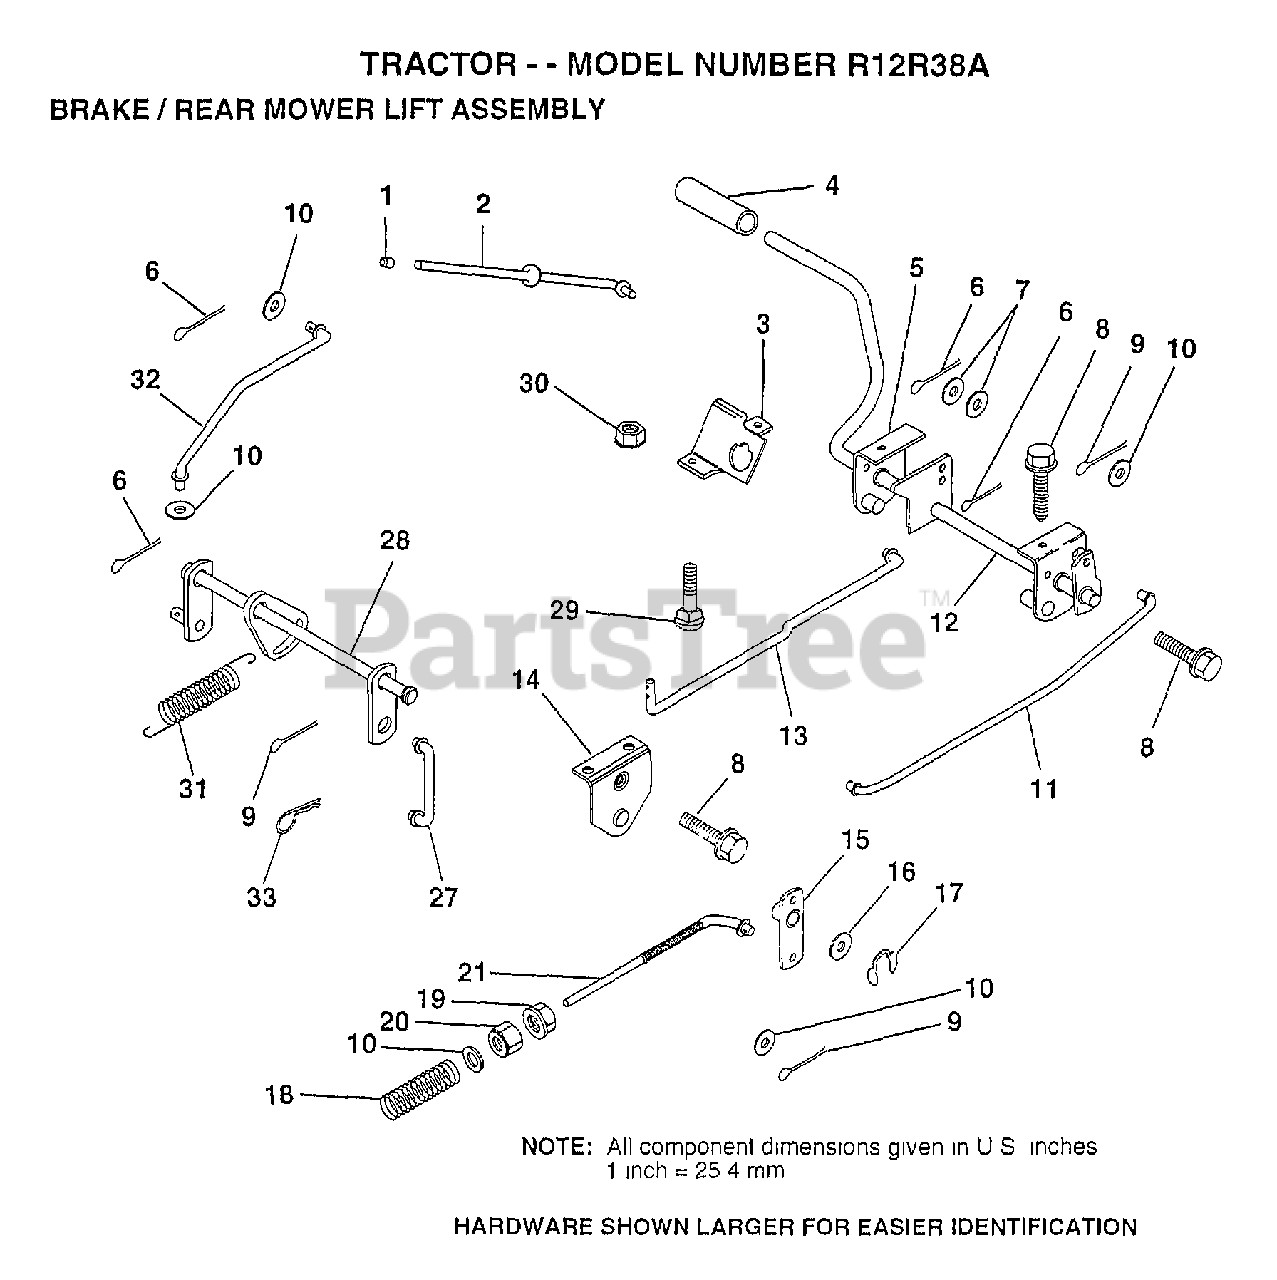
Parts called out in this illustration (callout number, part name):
1	PLUNGER CAP T
2	"ROD,PARK BRAKE"
3	"BRKT,PARK BRAKE"
4	FOOT PEDAL COVER
5	BRK ASM CLUT LH
7	WASHER
8	SCREW LT
9	COTTER PIN
10	WASHER
12	PEDAL ASM CLU/BRK
13	"ROD,CLUTCH"
14	"BRKT,LIFT SHAFT"
15	PVT BRAKE ARM ASM
16	WASHER T
17	KLIP RING
18	SPRING ROD BRAKE
19	NUT
20	NUT
27	LINK LIFT REAR LR
28	LIFT.ASM.REAR.LR
31	COUNTER SPRING
32	LINK LIFT LEVER
